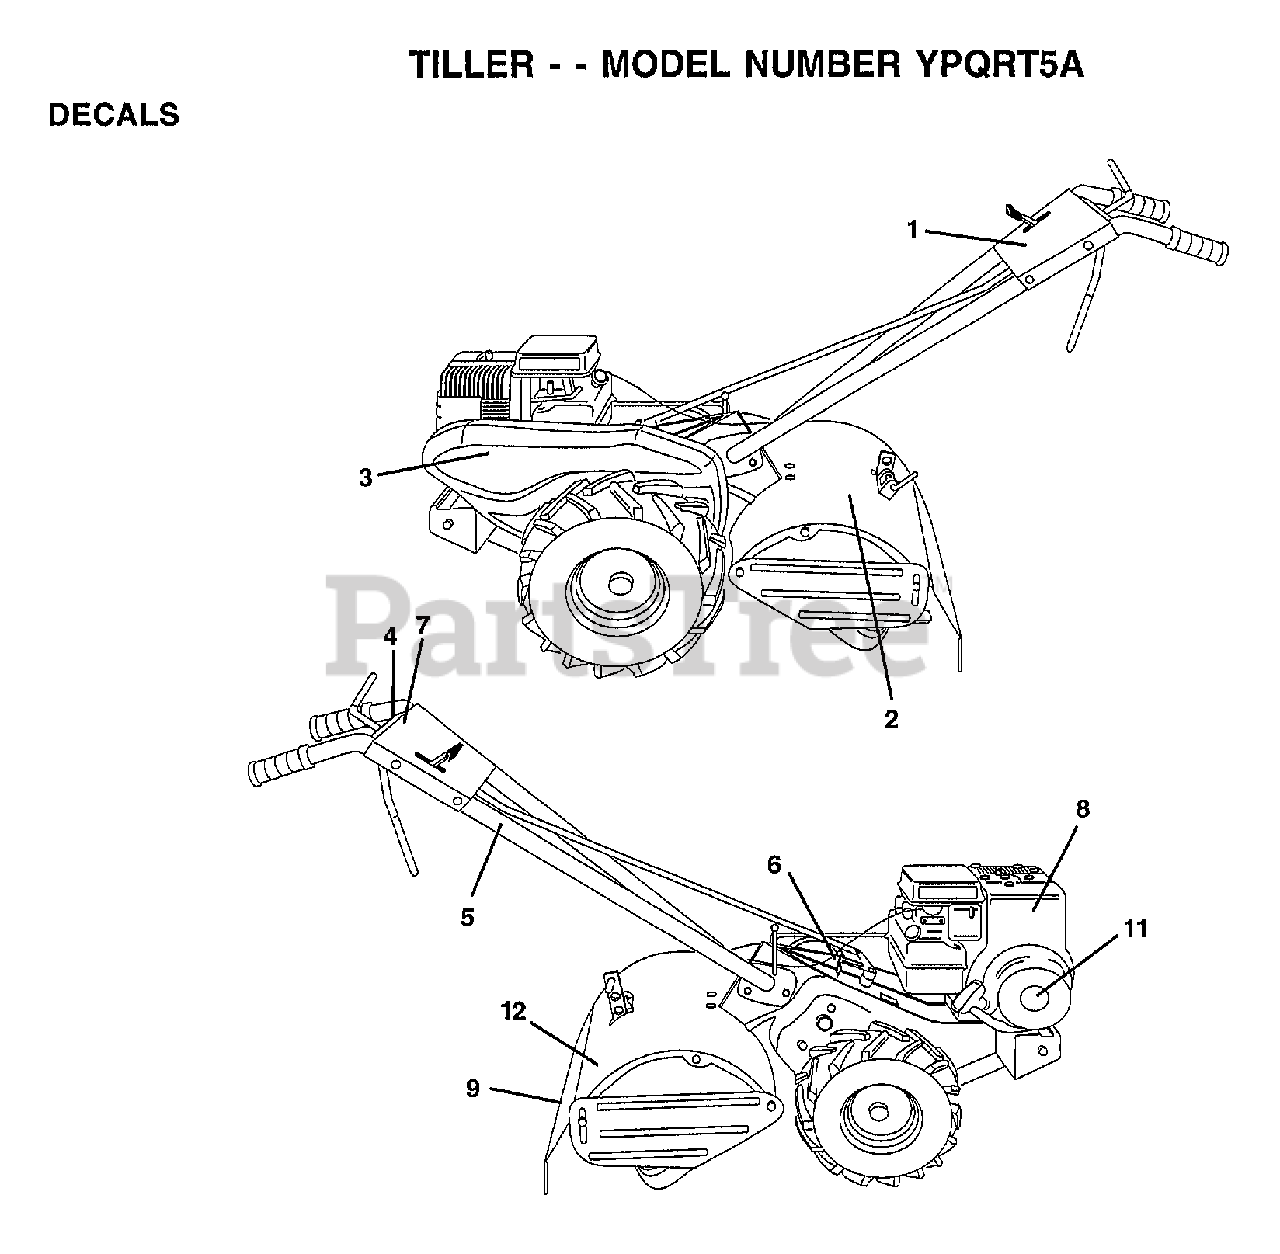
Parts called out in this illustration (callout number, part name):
1	DECAL, LOGO
2	DECAL SHIELD TINE
3	DECAL LOGO BELT GUARD
5	DECAL TI
6	DECAL CRT
7	DECAL REVERSE
12	DECAL.CAUTION
